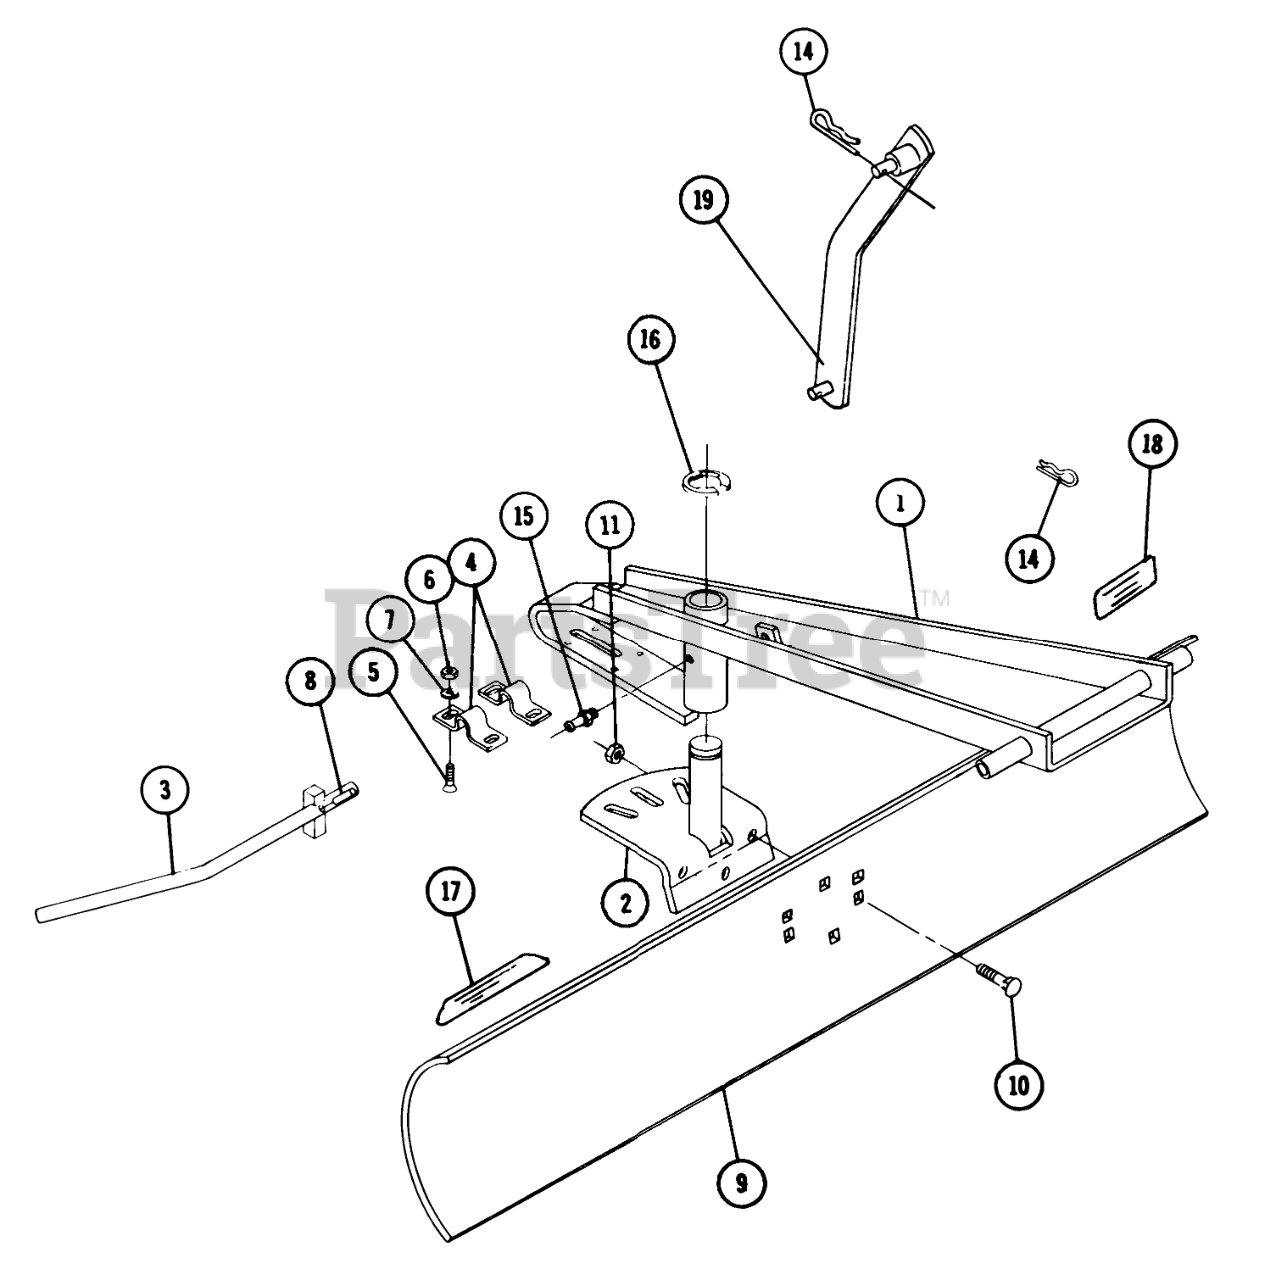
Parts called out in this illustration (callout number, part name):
1	Frame Assembly
2	Blade Support
3	Rod-Angle Adjustment
4	Bracket
5	Screw 1/4-20 x 5/8 Mach. Rd. Hd. Slotted
6	Nut
7	WASHER
8	PIN-ROLL
9	Blade
10	Bolt
11	Nut
13	Pin
14	Hairpin
15	Zerk
16	E RING
17	DECAL-WHEEL HORSE
18	Surfacing-Die Cut
19	Lift Link
